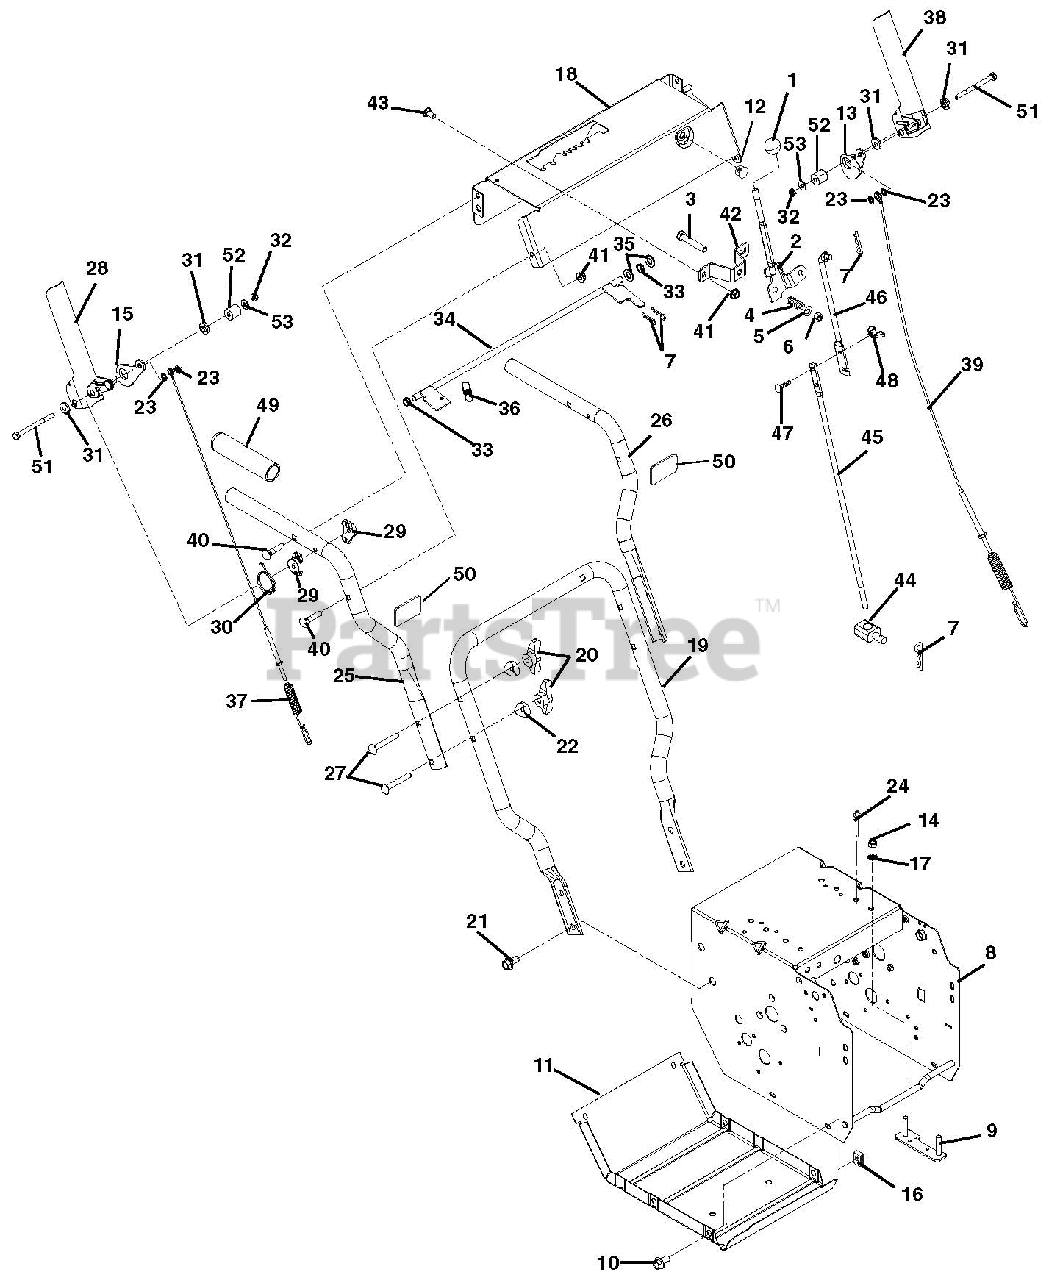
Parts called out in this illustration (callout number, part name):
1	KNOB,BALL -BLACK 1.47" .375-16
2	WMT, SHIFT LEVER
3	@BLT-HEX .38-16X2.00 GR5 YWZC
4	SG-COMP .125X.781X1.250
5	@WSHR-FL-STL.438X1.00X.083 YWZ
6	@NUT-LK-CTR .38-16 YWZC
7	PIN-HAIR INT .08X.18X1.18 YWZC
8	WELDMENT, FRAME
9	STRAP, ENGINE BOLT-WELDMENT
10	BLT-HEX .25-20X.75 HWH YZ GR5
11	COVER, BOTTOM
12	HOLE PLUG, PLASTIC .44 HOLE
13	LH CAM, INTERLOCK
14	@NUT-HEX .31-18 YWZC
15	RH CAM, INTERLOCK
16	NUT-RTNR .25-20X.56
17	WSHR-LK .312X.097 HVY YWZC
18	CONTROL PANEL W/DECAL
19	HANDLEBAR, LOWER - COMPACT
20	KNOB - WING .312-18 UNC
21	BLT-SERHFWH .38-16X.75 YWZC
22	SPACER, HANDLEBAR
23	RG-RTNG-EXT .250X.010
24	RVT-POP .187 YZ
25	HANDLEBAR, UPPER - RH COMP/DEL
26	HANDLEBAR, UPPER - LH COMP/DEL
27	@BLT-RDHDSQNK .31-18X2.25 G5YZ
28	PADDLE, CLUTCH - RH COMPACT
29	SPACER, HANDLEBAR
30	SPRING, TORSION
31	BSHG, FLG .266X.42X.150 PM
32	NUT-JAM-NYL .250-20 W/INSERTYZ
33	BUSHING, POLYLINER-.38 SNAPIN
34	WMT,INTERLOCK SHAFT
35	@WSHR-FL-STL.406X.812X.065 YWZ
36	SPRING, EXTENSION
37	CABLE, ATTACHMENT, COMPACT
38	PADDLE, CLUTCH - LH COMPACT
39	CABLE, TRACTION - COMPACT
40	BLT-RDHDXLSQNK .31-18X1.5 G5YZ
41	@NUT-LK-TOP-FLG .31-18 YWZC
42	BRACKET, SHIFT MOUNT
43	@BLT-RHDSSQNK .31-18X.62 G5YZ
44	PIVOT,SHIFT ROD .375-16(TRUNN)
45	ROD, SHIFT - LOWER
46	ROD, SHIFT - UPPER
47	@BLT-RDHDSQNK .25-20X.75 G5YZ
48	NUT-LK WING .250-20 YWZC
49	HANDLE GRIP
50	BUMPER PAD
51	@BLT-HEX .25-20X3.25 YWZC
52	BSHG, SLV .266 X .750 X .750
53	@WSHR-FL-STL.281X.62X.065 YWZC
